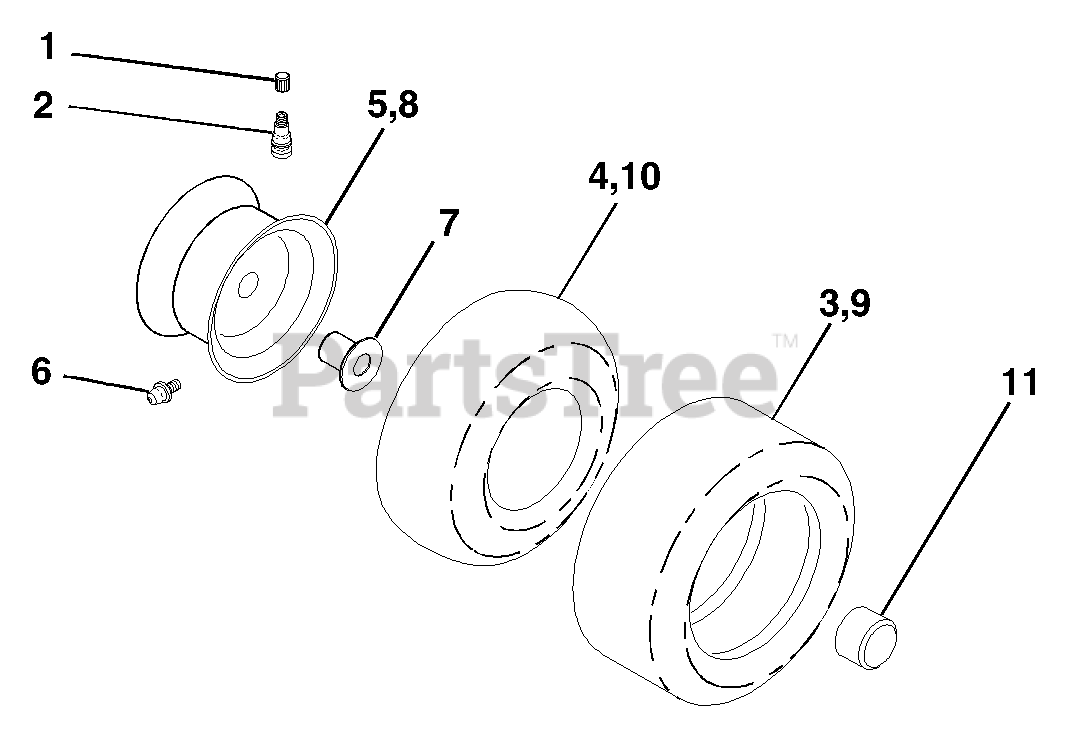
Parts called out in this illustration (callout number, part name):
1	Cap Valve Tire
2	Stem Valve
3	Tire F Ts 15 X 6 0 - 6 Service
4	Tube Front (Service Item Only)
5	Rim Asm 6"front Silver Service
6	Fitting Grease (Front Wheel Only)
7	Bearing Flange (Front Wheel Only)
8	Rim Asm 8"rear Silver Service
9	Tire R Ts 18x9 5-8 C Service
10	Tube Rear (Service Item Only)
11	Cap Axle Blk 1 50 X 1 00
